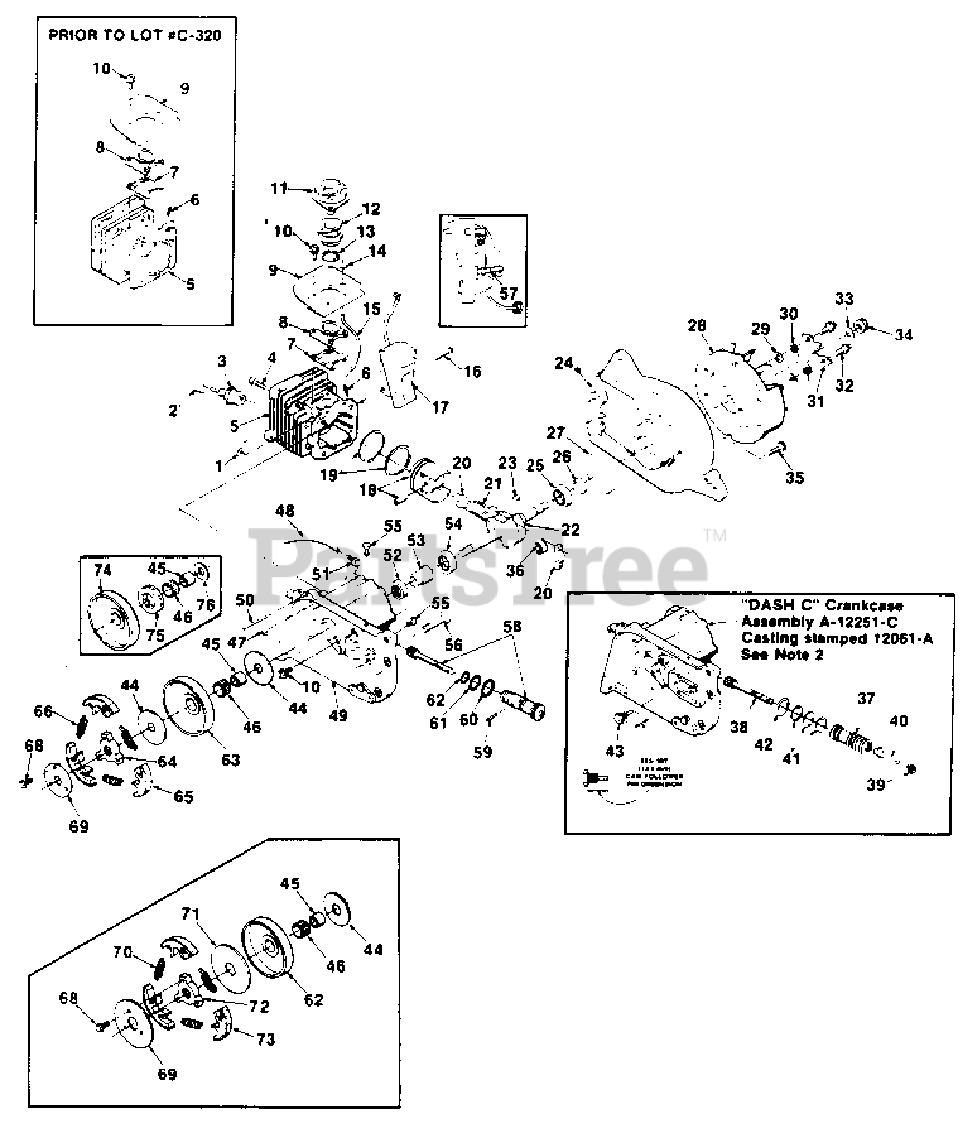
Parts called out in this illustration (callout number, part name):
2	GROMMET- Spark plug
3	SPARK PLUG (Champ CJ6)
4	SCREW- Soc. hd. cap #10-24 x 7/8
5	CYLINDER (Prior to lot #C-320)
6	FITTING
7	GASKET- Intake adapter
8	MANIFOLD- Intake
9	DEFLECTOR- Air (Intake)
10	SCREW- Hex hd. w/washer 8-32 x 1/2
11	FLANGE- Carburetor connector
12	CONNECTOR- Carburetor
13	SPRING- Garter
14	GROMMET
15	LINE- Pulse 5 1/2"
16	SCREW- Hex sems 8-32 x 1 1/4
17	MODULE & CORE
18	PISTON & PIN
19	PISTON RING
20	ROD- Connecting
21	SCREW- Soc. hd. 80-32 x 9/16
22	CRANKSHAFT
23	KEY- Woodruff
24	PLATE- Back
25	BEARING- Roller
26	SEAL
27	O" RING
29	WASHER- Lock #10
30	SPRING- Starter pawl
31	PAWL- Starter
32	STUD- Starter pawl
33	WASHER- 3/8"
34	NUT- 3/8 - 24
35	SCREW- Hex sems 10-24 x 3/4
36	ROLLERS- Needle (Set of 25)
37	PUMP- Automatic Oil
38	PLUNGER- Oil pump
39	SCREW- Hex sems 8-32 x 3/8
40	LEVER- Oil Adjustment
41	"O" RING
42	"O" RING
43	PIN & PLUG
44	WASHER- Thrust
45	RACE- Inner
46	BEARING- Needle
47	NUT- Centerlock #10-24
48	TUBING-Rubber (0il) 4 3/4"
49	CRANKCASE
50	PIN- Dowel (.125 x 1.375) Install in crankcase for chain brake only Pin #14 supplied loose in SL chain brake kit and 360 service crankcase assy,
51	FITTING- Oil line
52	SEAL- (Double lips)
53	WORM- Gear
54	BEARING- Roller
56	BOLT- Guide bar 5/16"
57	CABLE TIE- Module lead
58	PUMP- Automatic Oil
59	PIN- Pump
60	"O" RING
61	"O" RING
62	"O" RING
63	SPROCKET & DRUM 7T, 3/8 P
64	SPIDER Clutch (After lot #C-320)
65	SHOE- Clutch (After lot #C-320)
66	SPRING- Extension (After lot #C-320)
68	SCREW- Hex sems 8-32 x .375
69	COVER- Clutch (Prior to lot #C-320)
70	SPRING- Clutch (Prior to lot #C-320)
71	WASHER- Thrust (Prior to lot #C-320)
72	SPIDER- Clutch (Prior to lot #C-320)
73	SHOE- Clutch (Prior to Lot #C-320)
74	DRUM & HUB
75	SPROCKET & RIM 7T 3/8 P (Primary source)
76	WASHER- Thrust (Inner) (Prior to Lot #C-320)
